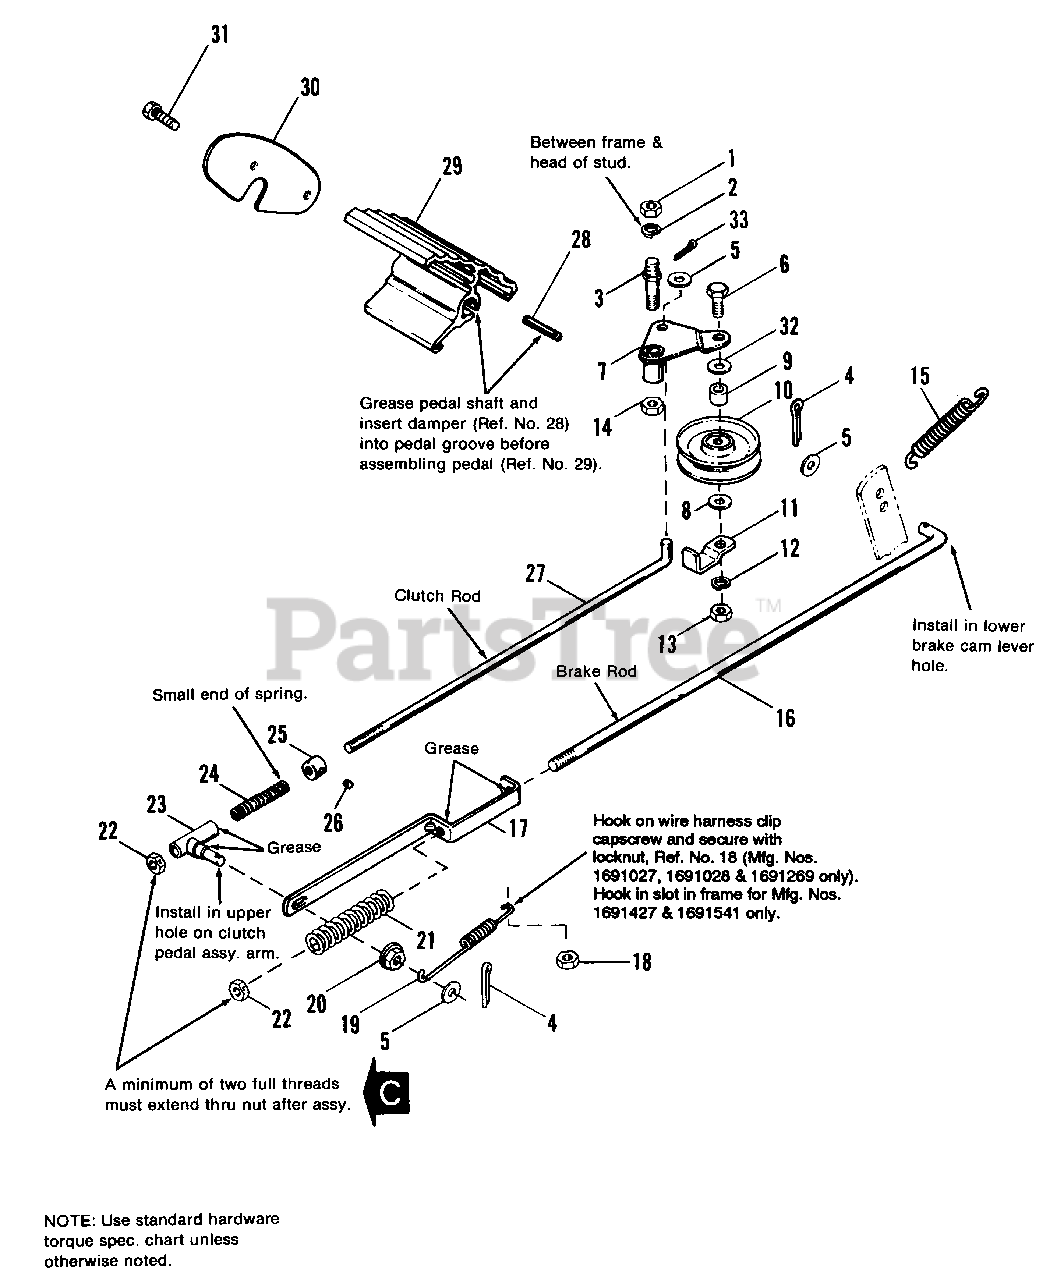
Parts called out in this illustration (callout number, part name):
1	NUT, Hex, 7/16-14
2	LOCKWASHER, 7/16
4	PIN, Cotter
5	WASHER, 11/32
6	CAPSCREW, 3/8-16 x 1-1/2
7	IDLER ASSY.
8	WASHER, Plain, 5/16
10	PULLEY ASSY.
11	GUARD, Spring
12	LOCKWASHER, 3/8
13	NUT, Hex, 3/8-16
14	LOCKNUT, Hex, 7/16-14
15	SPRING, Tension
18	LOCKNUT, Hex, 5/16-18 (Used on 1691027, 1691028, 1691269 only)
19	SPRING, Return
20	LOCKNUT, Hex, Flange, 5/16-18
22	LOCKNUT, 5/16-18
23	GUIDE ASSY., Rod
24	SPRING, Compression
25	COLLAR, Set
26	SETSCREW, 1/4-20 x 3/8
27	ROD, Clutch
28	DAMPER, Rubber
29	PEDAL, Foot
30	PLATE, End
31	SCREW, Taptite, 1/4-20 x 5/8
32	WASHER, Plain
33	PIN, Cotter
